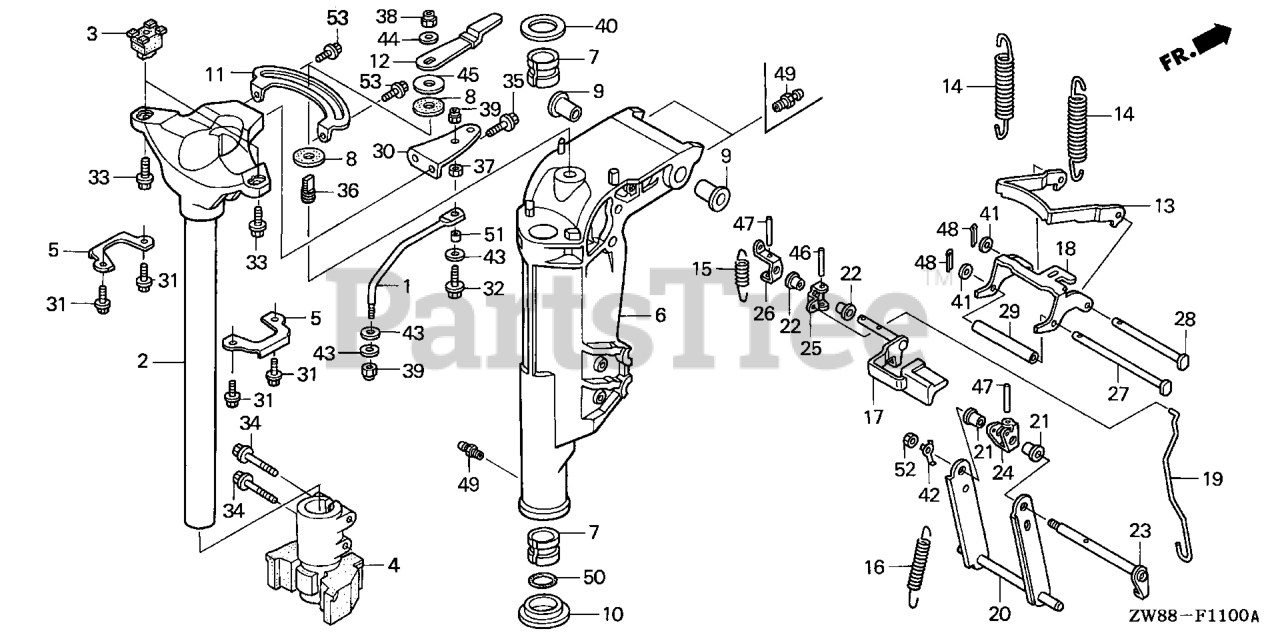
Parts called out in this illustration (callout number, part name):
2	FRAME, MOUNTING (L)
3	RUBBER, MOUNTING (UPPER)
4	RUBBER, MOUNTING (LOWER)
5	COVER, MOUNTING RUBBER (UPPER)
6	CASE, SWIVEL *NH282MU* (L) (OYSTER SILVER METALLIC-U)
7	LINER, SWIVEL CASE
8	BLOCK, FRICTION
9	BUSH, SWIVEL CASE
10	COLLAR, SWIVEL CASE
11	PLATE, FRICTION
12	LEVER, FRICTION
13	HOOK, REVERSE LOCK
14	SPRING, REVERSE LOCK
15	SPRING, TILT LEVER
16	SPRING, TILT LINK
17	LEVER, TILT
18	ARM, REVERSE LOCK
19	ROD, RELEASE SWIVEL CASE
20	ARM, TILT
21	BUSH, TILT LEVER
22	BUSH, TILT LEVER
23	SHAFT, TILT
24	BRACKET, TILT SHAFT
25	BRACKET, RELEASE ROD
26	BRACKET, TILT LEVER
27	SHAFT, REVERSE LOCK (A)
28	SHAFT, REVERSE LOCK (B)
29	COLLAR, REVERSE LOCK
31	BOLT, FLANGE (6X12) Use from Frame SN 1005249.
33	BOLT, FLANGE (10X25)
34	BOLT, FLANGE (8X45)
36	BOLT, STUD (8X26)
38	NUT, SELF-LOCK (8MM)
40	WASHER, THRUST
41	WASHER, PLAIN (6MM) Use from Frame SN 4800713.
42	WASHER, LOCK
44	WASHER (8MM)
45	WASHER, NYLON (8MM)
46	PIN, SPRING (3.0X22)
47	PIN, SPRING (3.0X25)
48	PIN, SPLIT (2.0)
49	NIPPLE, GREASE
50	O-RING (34X2.4)
52	NUT, HEX. (6MM)
53	BOLT, FLANGE (6X12)
